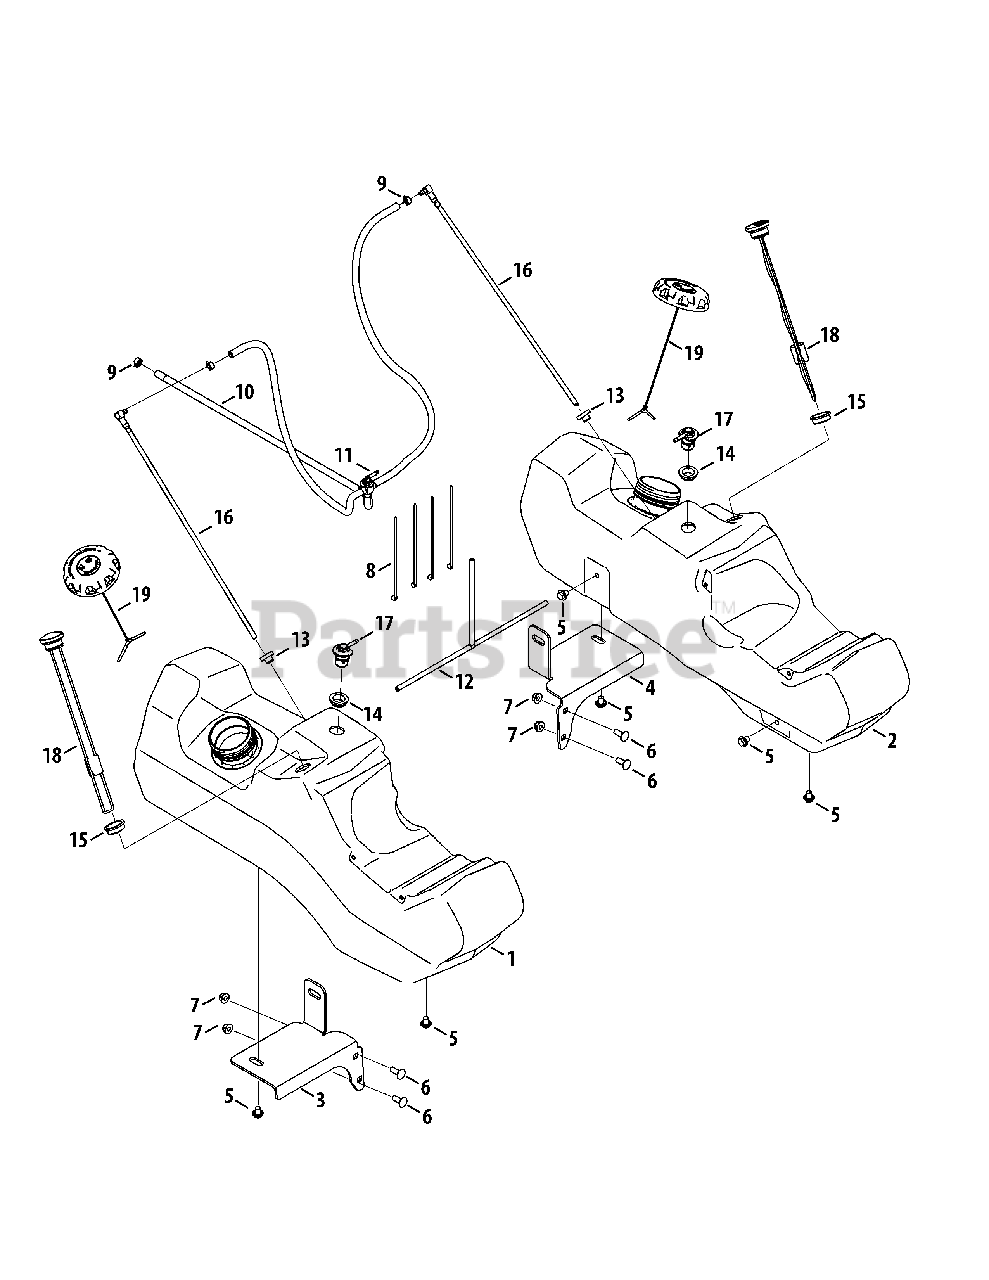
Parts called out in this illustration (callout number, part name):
1	Fuel Tank Assembly, RH
2	Fuel Tank Assembly, LH
3	Rear Fuel Bracket, RH
4	Rear Fuel Bracket, LH
5	Hex Cap Screw, 3/8-16 x .500
6	Carriage Bolt, 3/8-16 x .500
7	Nut, 3/8-16, Flangelock
8	Cable Tie
9	Hose Clamp, .500 Dia.
10	Fuel Hose., 1/4
11	Fuel Switch
12	Fuel Hose Assembly includes:
12	Hose, 3/16" Fuel Line (in inches)
12	Tee Fitting, Fuel
13	Grommet, Fuel Tank
14	Grommet, .755 x .955 x .55
15	Grommet, 1.58 OD x 1.21 ID x .5
16	Fuel Pickup Valve
17	Fuel Rollover Valve
18	Fuel Gauge
